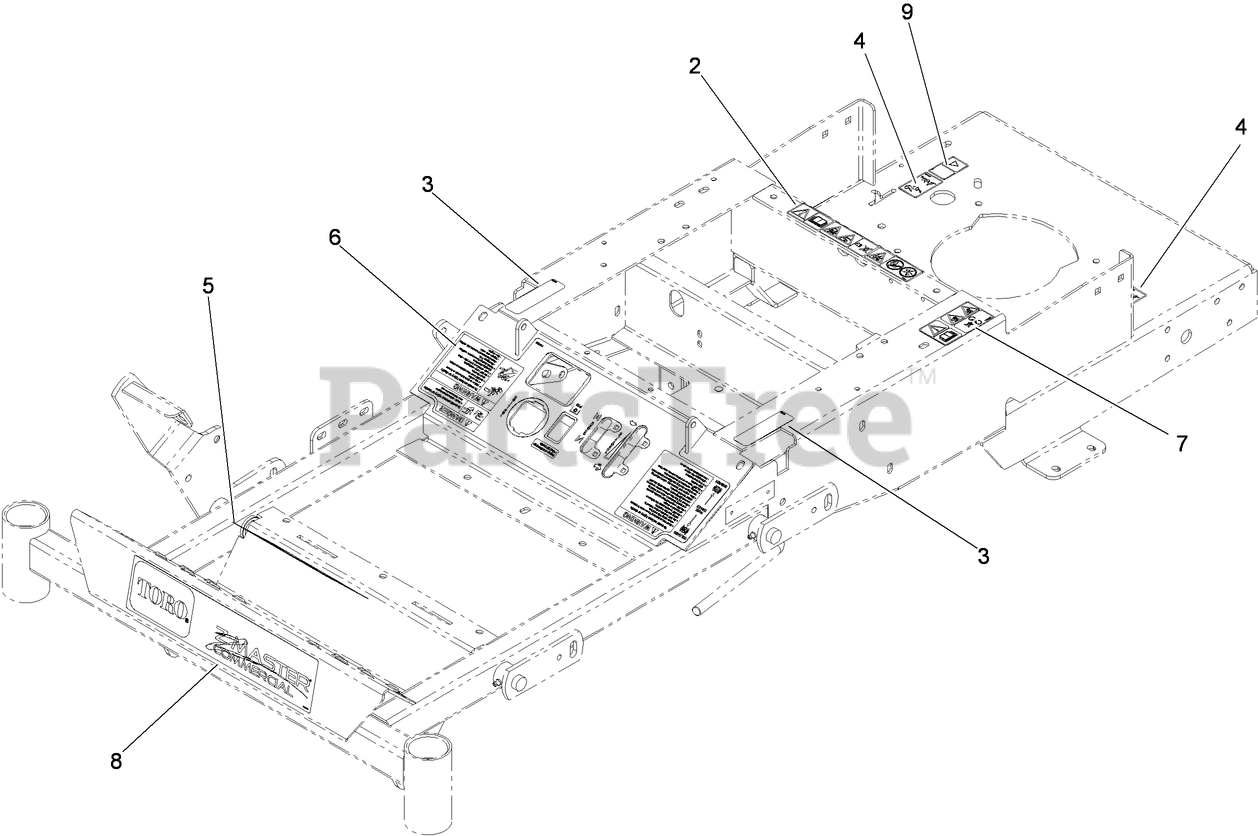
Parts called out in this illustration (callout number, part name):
2	DECAL-DANGER BATTERY, CE
3	DECAL-CONTROL, MOTION
4	DECAL-TRANSPORT, CE
5	DECAL-DANGER SLOPE, CE
6	DECAL-CONSOLE
7	DECAL-DANGER, CE
9	DECAL-SURFACE, HOT
